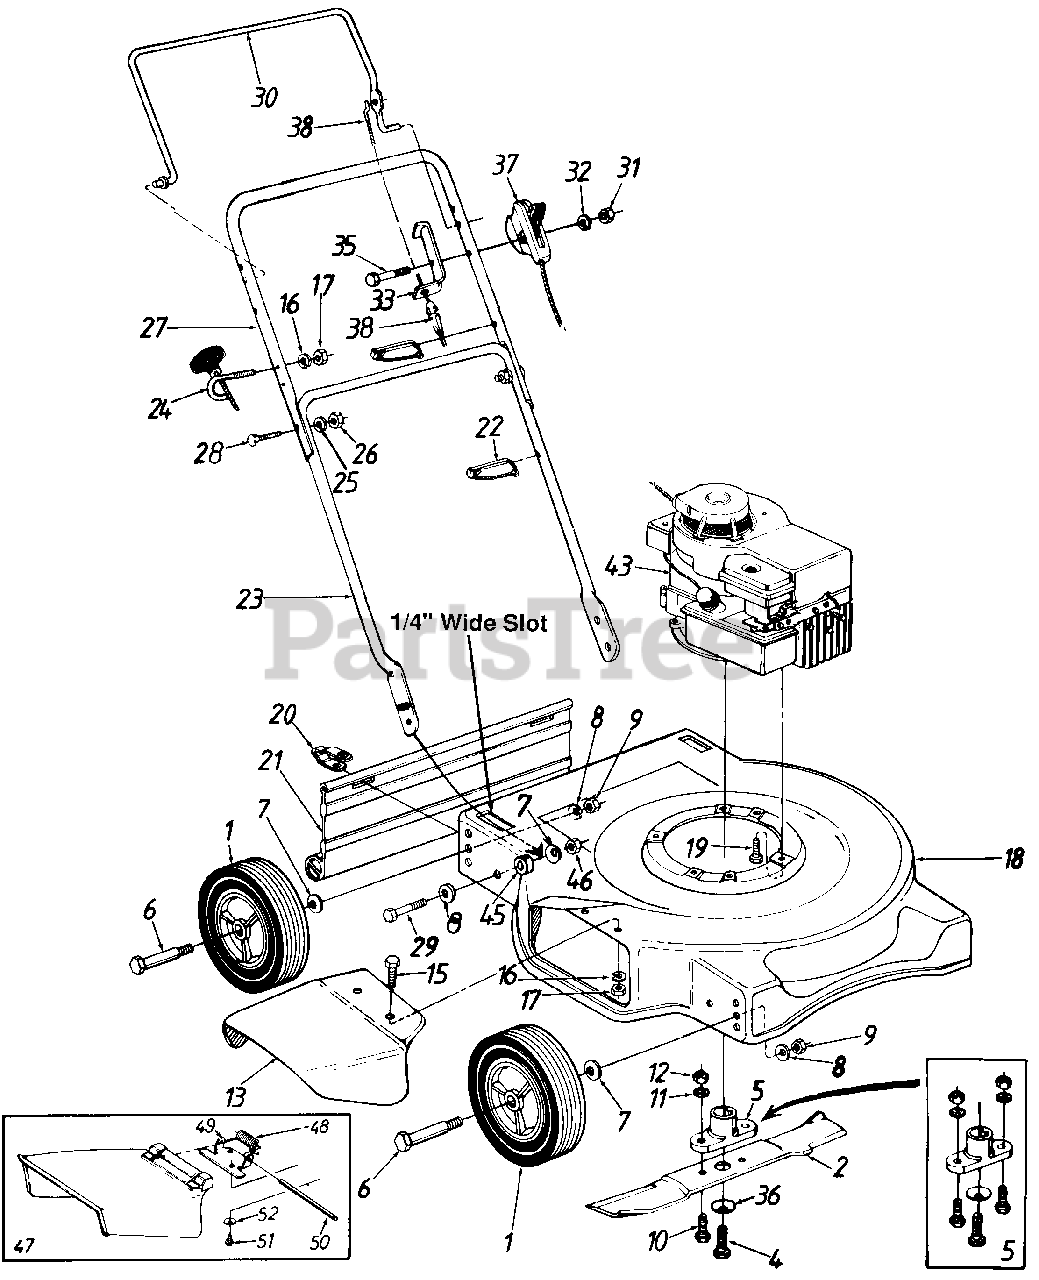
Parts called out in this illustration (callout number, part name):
1	Wheel Ass'y. Complete
2	20" Blade
4	Hex Bolt 3/8-24 x 1.5" Lg.
5	Blade Adapter Kit (Keyed)
6	Axle Bolt
7	Bell-Wash. .380" I.D. x .88"
8	Bell-Wash. .39" I.D. x 1.13"
9	Hex Nut 3/8-16 Thd.
10	Hex Bolt 3/8-24 x 1" Lg.
11	L-Wash. 3/8" I.D.
12	Hex Nut 3/8-24 Thd.
13	Chute Deflectort
15	Hex Bolt 1/4-20 x .5" Lg.
16	L-Wash. 1/4" I.D.
17	Hex Nut 1/4-20 Thd.
18	20" Deck Ass'y.
19	Hex Wash. Hd. Scr. 3/8-16 x 1" Lg.
20	Hinge Clip
21	Rear Flap 16.75" Lg.
22	Cable Tie
23	Lower Handle
25	L-Wash. 5/16" I.D.
26	Hex Nut 5/16-18 Thd.
27	Upper Handle
28	Curved Carriage Bolt 5/16-18 x 1.38" Lg.
29	Hex Bolt 3/8-24 x 1.25" Lg.
30	Control Handle
31	Hex Nut 1/4-20 Thd.
32	Spr. Wash. .265" I.D. x .562"
33	Cable Mounting Bracket
35	Hex Bolt 1/4-20 x 1.75" Lg.
36	Bell-Wash. .39" I.D.
37	Throttle Control Ass'y. Comp.
38	Control Cable-36"
43	Engine
45	Spacer
46	Hex L-Nut 3/8-24 Thd.
47	Chute Deflector Ass'y. Comp.
48	Torsion Spring
49	Adapter Plate
50	Hinge Pin
51	Hex Self-Tap Scr. 1/4-20 x .5" Lg.
52	Beil-Wash 1/4" I.D
